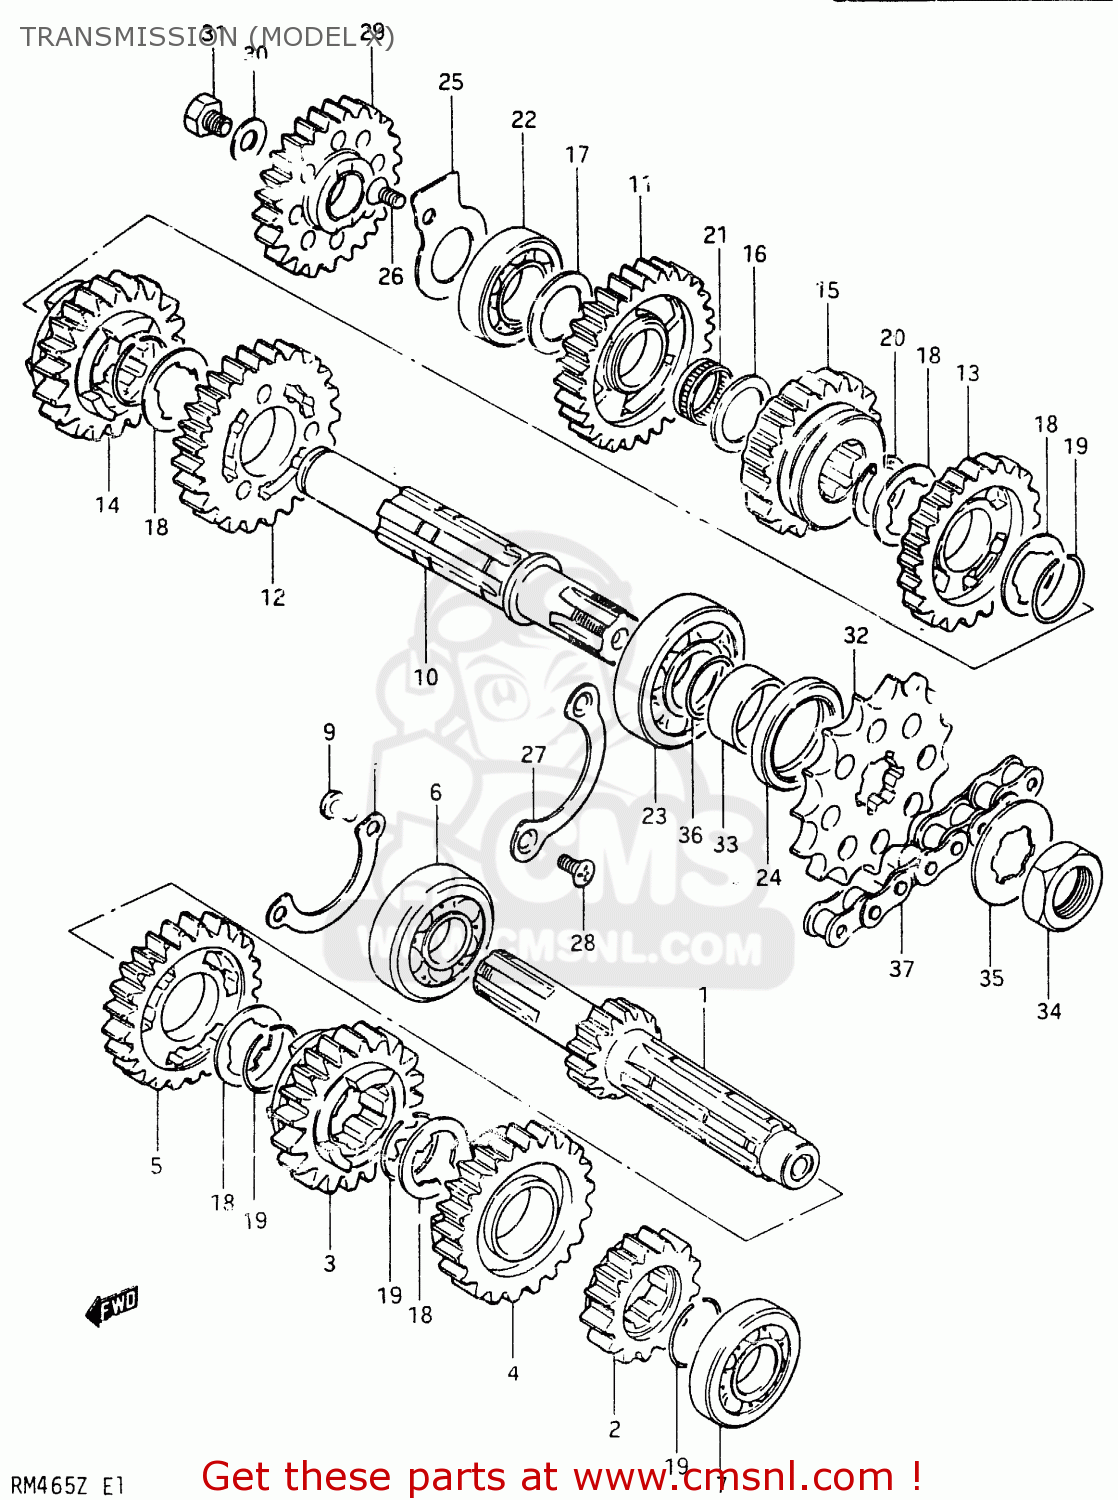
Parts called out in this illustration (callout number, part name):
1	SHAFT,COUNTER
2	GEAR,SECOND DRIVE
3	GEAR,THIRD DRIVE
4	GEAR,FOURTH DRIVE
5	GEAR,FIFTH DRIVE
6	BEARING
7	BEARING, LH
8	RETAINER,BEARING
9	SCREW 6X12
10	SHAFT,DRIVE
11	GEAR,FIRST DRIVEN
12	GEAR,SECOND DRIVEN
13	GEAR,THIRD DRIVEN
14	GEAR,FOURTH DRIVEN
15	GEAR,FIFTH DRIVEN
16	WASHER
17	WASHER
18	WASHER,LOCK
19	RING,SNAP
20	CIRCLIP
21	BEARING(20X24X10).8
22	BEARING
23	BEARING(22X56X16)
24	SEAL,OIL(32X42X6)
25	RETAINER,DRIVESHAFT
26	SCREW
27	PLATE,DRIVESHAFT BEARING
28	SCREW
29	GEAR,KICK STARTER IDLE
30	WASHER,THRUST
31	BOLT
32	SPROCKET,ENGINE
33	SPACER(22X32X11.5)
34	NUT
35	WASHER,LOCK
36	O RING(D:1.7,ID:22)
37	CHAIN ASSEMBLY,DRIVE
